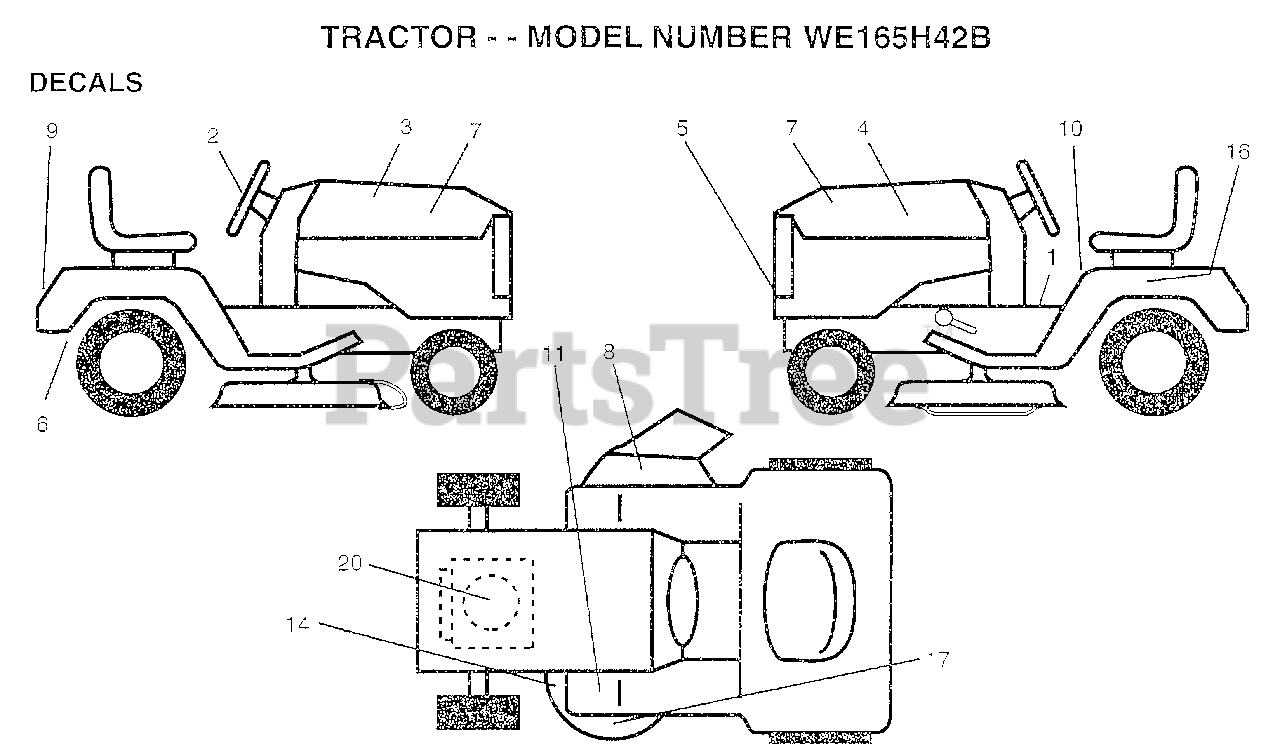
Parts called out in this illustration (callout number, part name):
1	DECAL SADDLE OPER
2	DECAL, INS STRG WH
3	DECAL.HOOD.RH.
4	DECAL.HOOD.LH
5	DECAL, GRILLE LENS
6	DECAL DRAWBAR LH
7	DECAL.PANEL.SIDE
8	"DECAL, WARNING"
9	DECAL.FENDER.LOGO
10	DECAL.CAUT.ENG/FR
11	DECAL T
14	"DECAL-SCHEM,BELT"
16	DECAL.BATRY.3-3908
17	DECAL, DECK GRASSEATER
20	DECAL ENGINE
